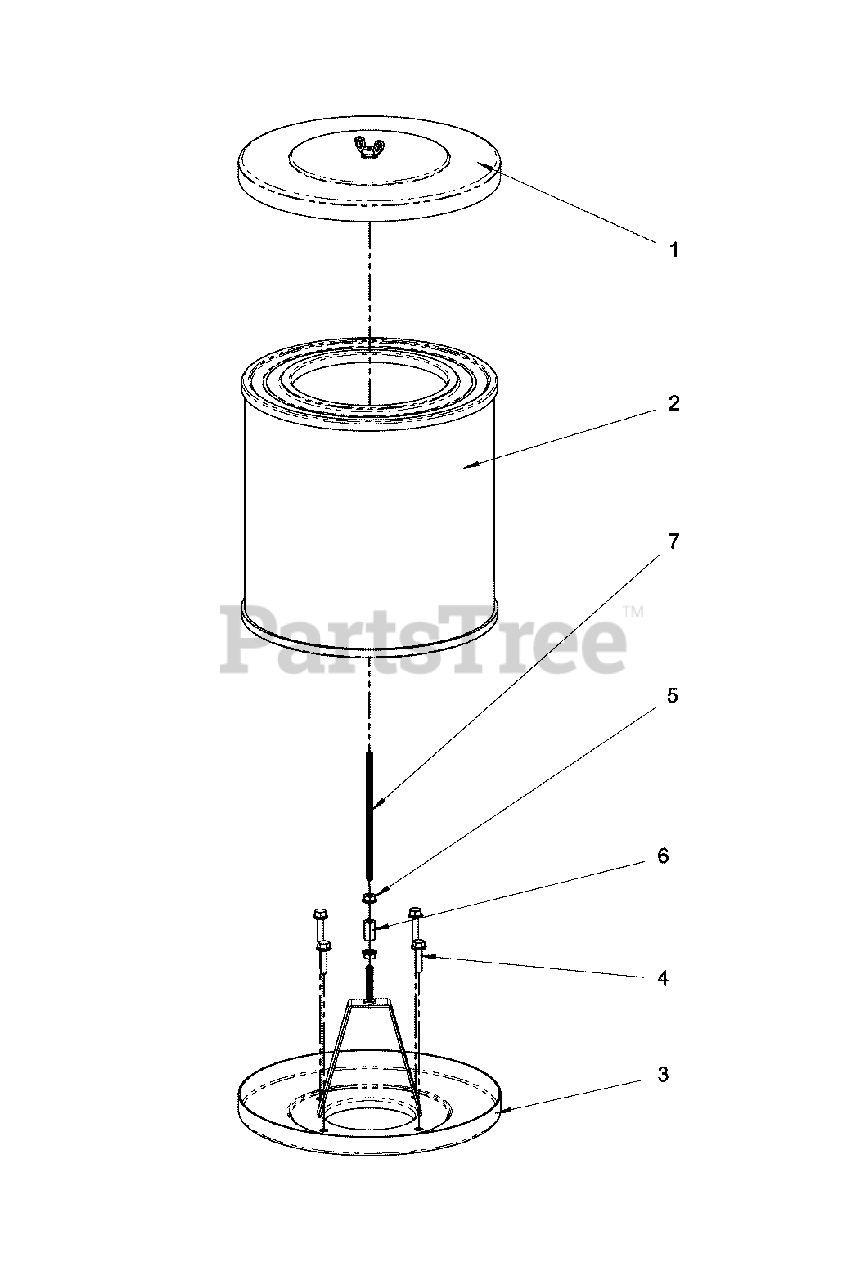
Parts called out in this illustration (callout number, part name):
1	* TOP
2	AIR FILTER ELEMENT
3	* BASE
4	* SCREW
5	* NUT
6	* EXTENDER ROD
7	* ROD
